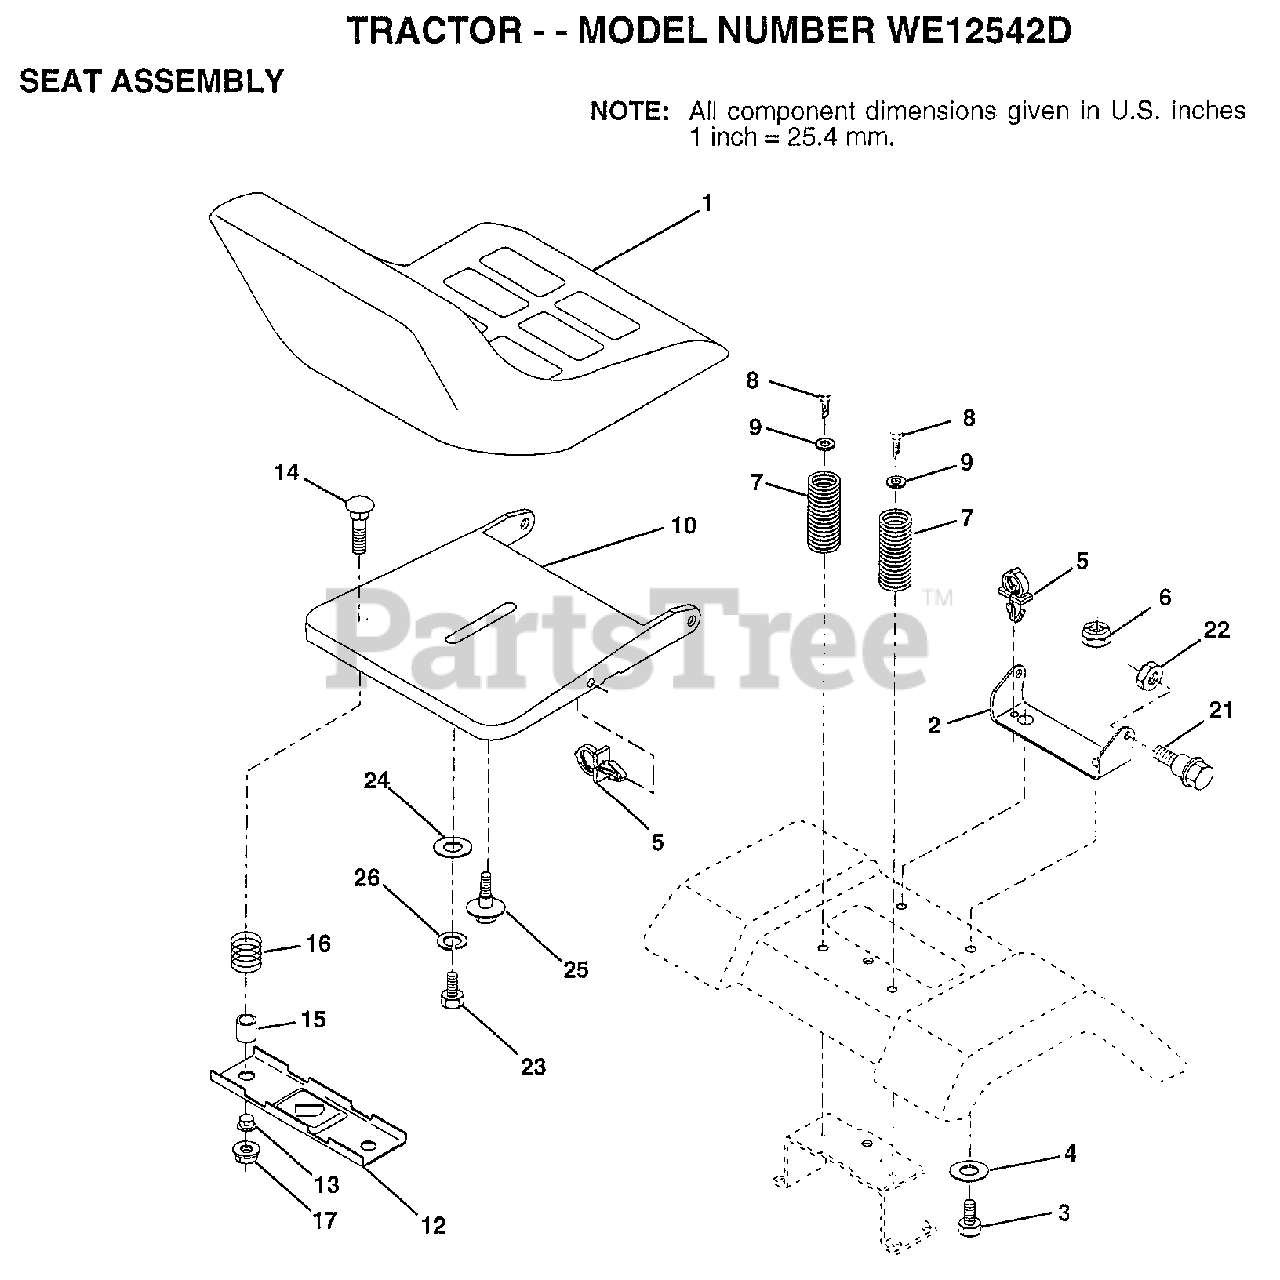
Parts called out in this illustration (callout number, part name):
2	BRACKET PVT SEAT
3	BOLT
4	WASHER PM
5	CLIP.PUSH-IN.HING
6	NUT
7	SPRING COMPRESSIO
8	SCREW GTV
9	WASHER
10	PAN-SEAT
12	BRKT SWITCH
13	BUSHING
14	BOLT-RD HD SQ NK
15	SPLIT SPACER
16	SPRING
21	"BOLT,SHOULDER"
22	NUT
23	BOLT
24	WASHER
25	"BOLT,SHOULDER"
26	LOCKWASHER
